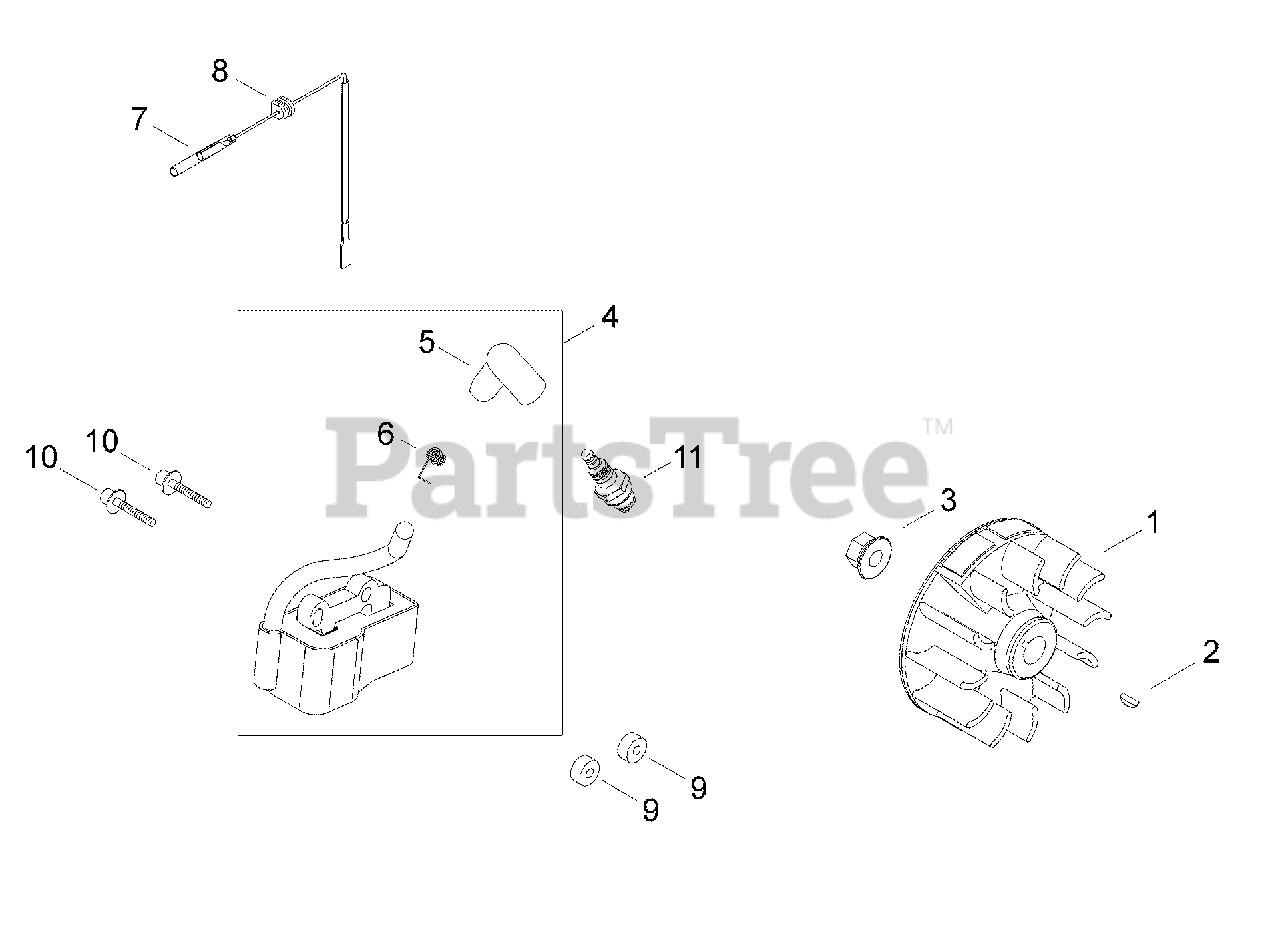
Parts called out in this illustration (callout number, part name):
1	FLYWHEEL
2	KEY, WOODRUFF 3×10
3	NUT M8
4	COIL ASSY, IGNITION
5	CAP, SPARK PLUG
6	TERMINAL, SPARK PLUG
7	LEAD - IGNITION
8	GROMMET, LEAD
9	INSULATOR 4.2×11×6
10	BOLT M4×26
11	SPARK PLUG - CMR5H
